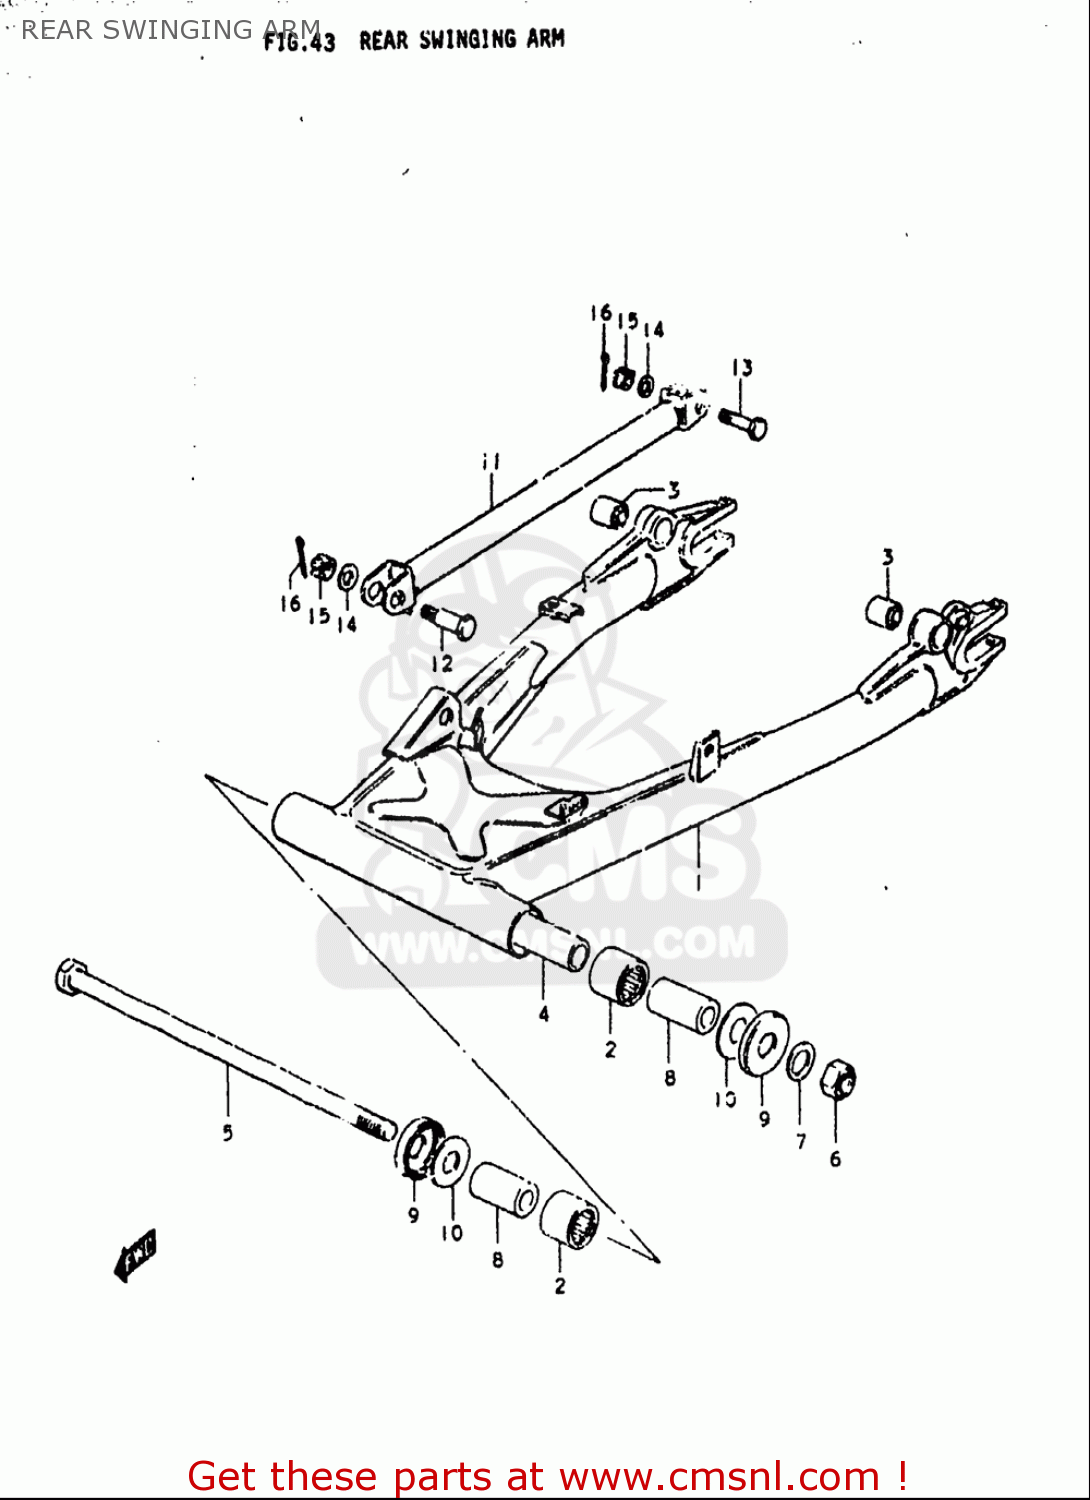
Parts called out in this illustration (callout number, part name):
2	BEARING(25X33X30)
3	BUSH
4	SPACER,RR SWGARM PIVOT CTR
5	SHAFT,RR SWINGINGARM PIVOT
6	NUT 16MM
7	WASHER
8	SPACER,RR SWGARM PIVOT
9	COVER,RR SWGARM DUST SEAL
10	WASHER
12	BOLT M10X39
13	BOLT(10X39)
14	WASHER
15	NUT
16	PIN
